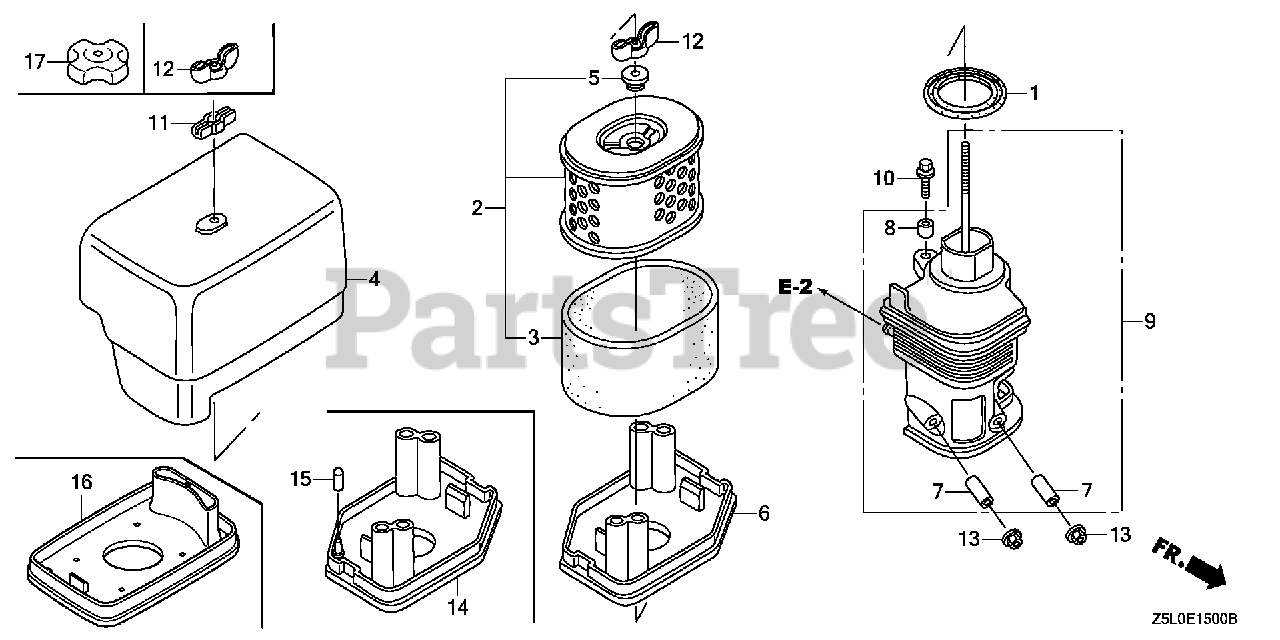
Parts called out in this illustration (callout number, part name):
1	GASKET, AIR CLEANER HOUSING
2	ELEMENT, AIR CLEANER
3	FILTER (OUTER)
4	COVER, AIR CLEANER HOUSING
5	GROMMET, AIR CLEANER
7	COLLAR, AIR CLEANER
8	COLLAR B, AIR CLEANER
9	ELBOW, AIR CLEANER
10	BOLT-WASHER (6X22)
12	WINGNUT, TOOL BOX SETTING
13	NUT, FLANGE (6MM)
16	NOSE, MUFFLER
17	NUT, AIR CLEANER COVER
